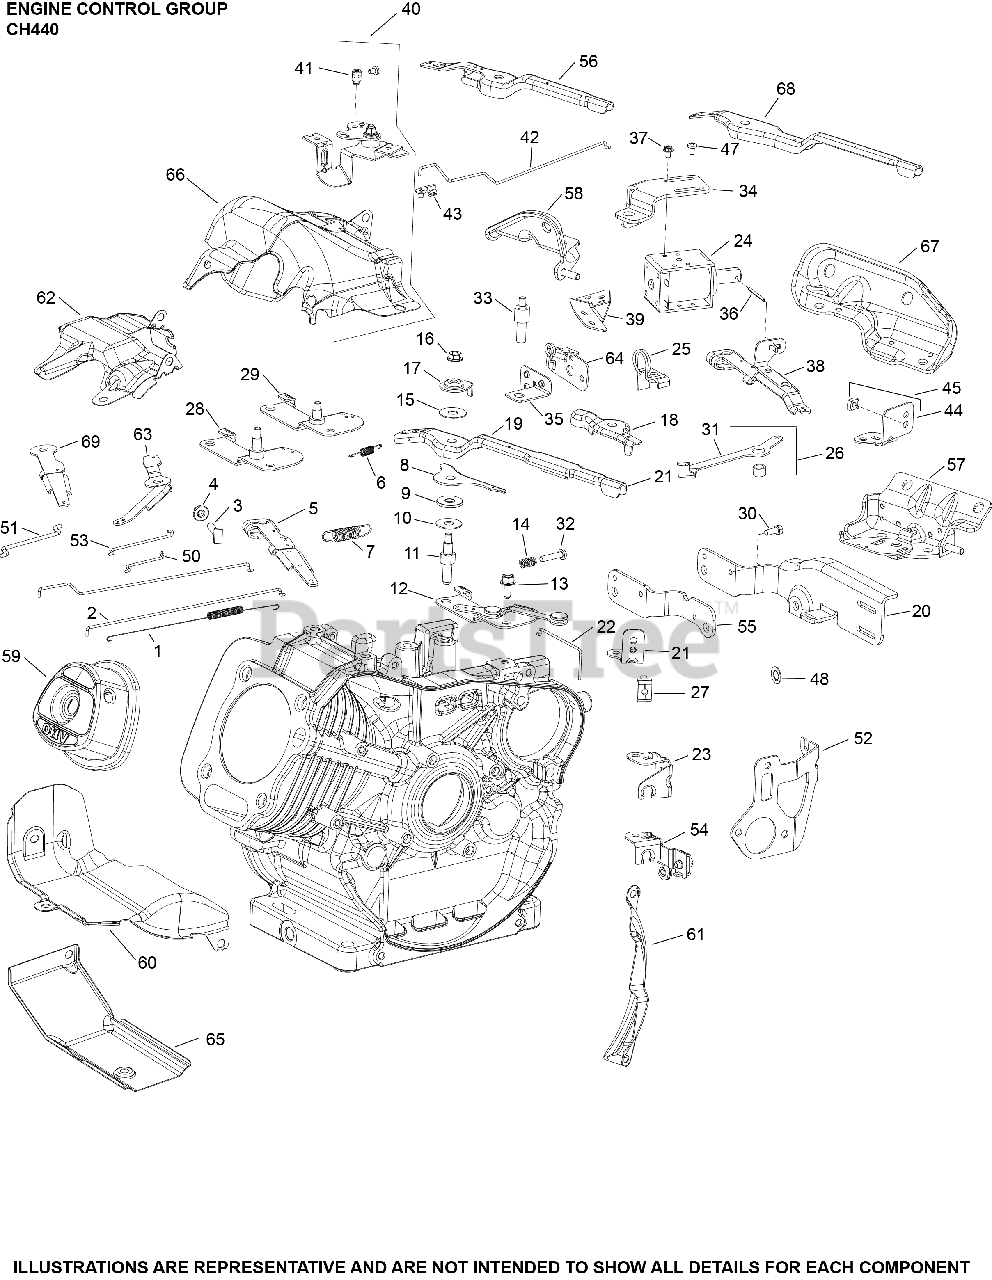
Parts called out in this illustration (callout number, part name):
1	SPRING, LINKAGE
2	LINKAGE, GOVERNOR
3	SCREW, RECTANGLE HEAD (M6)
4	NUT, HEX FLANGE (M6) - USE 14 100 16-S
5	KIT, GOVERNOR LEVER
7	SPRING, GOVERNOR
8	LEVER, FIXED SPEED
14	SPRING, COMPRESSION
16	NUT, HEX FLANGE LOCK (M6)
32	SCREW, SPEED ADJUSTING (CKY)
33	STUD, CONTROL LEVER
